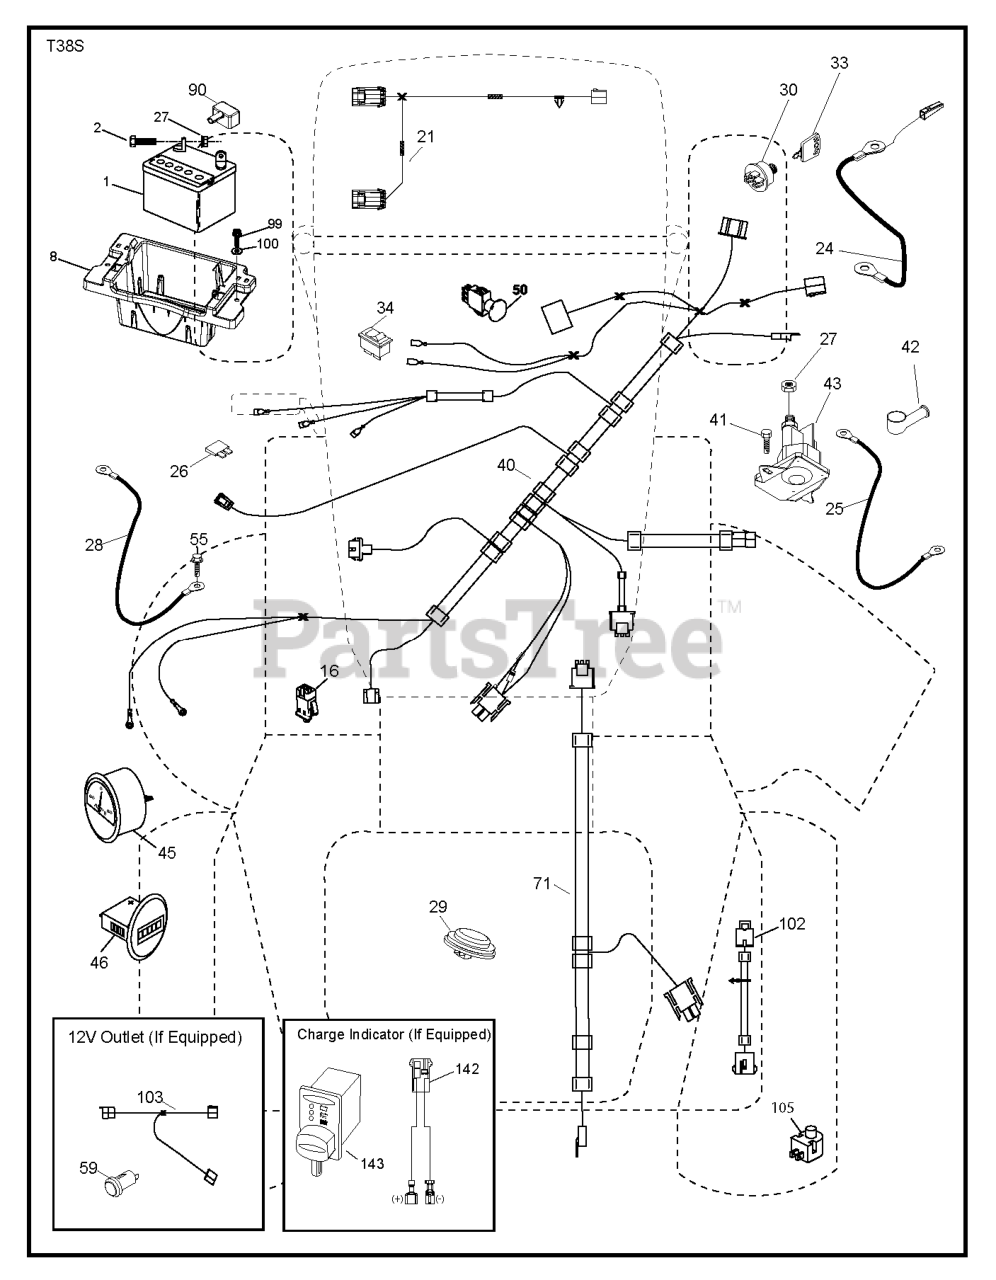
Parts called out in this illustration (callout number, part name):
1	Battery 12 Volt 25 Amp
2	BOLT.HEX.1/4.X.3/4.DICHROMATE
8	TRAY.BATTERY BOX.FRONT
16	SWITCH INTERLOOK PUSH-IN
21	HARNESS.LIGHT W/4152J BULBS
24	CABLE.FRBATT.W/WIRE.8GA.8
25	CABLE.STARTER.8GA.17.5
26	FUSE 20AMP
27	NUT
28	CABLE.GROUND.21"BLK.8GA.90T
29	SWITCH.SEAT.DP W/RAMPS
30	SWITCH.IGN.DELTA.W.LGH.ROS
33	KEY.CHAIN.BLISTER.PACK.GEN.INT
40	HARNESS HARNESS..DASH.ING.ELEC
41	SCREW
42	TERMINAL COVER
43	SOLENOID.STARTER.BRASS.PLUNGER
46	GUAGE.SRVCMNDR.HRMTR.
50	SWITCH.PTO.8TERMINAL.STD.BLK
55	SCREW 5/16"
71	HARNESS-CHASSIS SUB
79	BULB HOLDER ASM.
90	COVER.TERMINAL.BATTERY
99	SCREW HEXWSHR 1/4-20X3/4
102	HARNESS PIGTAIL PCH TEX ROS
103	HARNESS.PIGTAIL.12V.OUTLET.
105	REVERSE SWITCH
